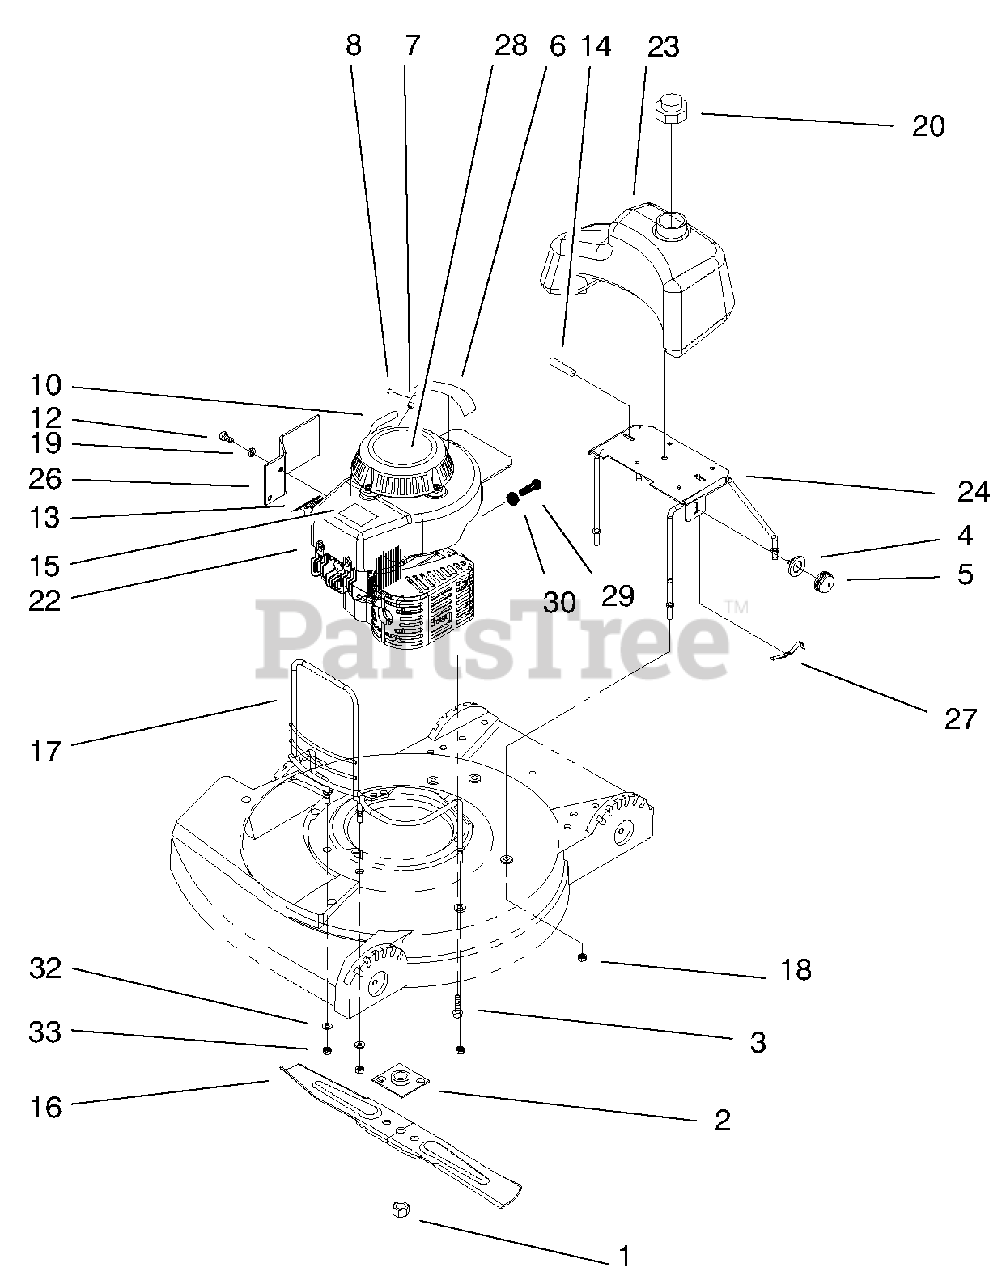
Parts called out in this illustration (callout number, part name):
1	NUT-BLADE
2	PLATE & COLLAR ASM
3	SCREW-HH, SEMS
4	BODY-PRIMER
5	BULB-PRIMER
6	DECAL-FUEL MIX
7	STOP-ROPE
10	LINE-FUEL
12	SCREW-HH
13	SPRING-COMPRESSION
14	PLUG-CAP
15	DECAL-LAWN BOY
16	Blade
17	GUARD-MUFFLER
18	NUT-LOCK F
19	WASHER-LOCK
20	FUEL & OIL CAP ASM
22	ENGINE ASM
23	TANK - FUEL
24	TANK BRACKET ASM
26	GUARD-BRAKE S
28	DECAL - RECOIL
30	NUT-HEX
32	WASHER-HOOD PIVOT
33	NUT-LOCK, NI
